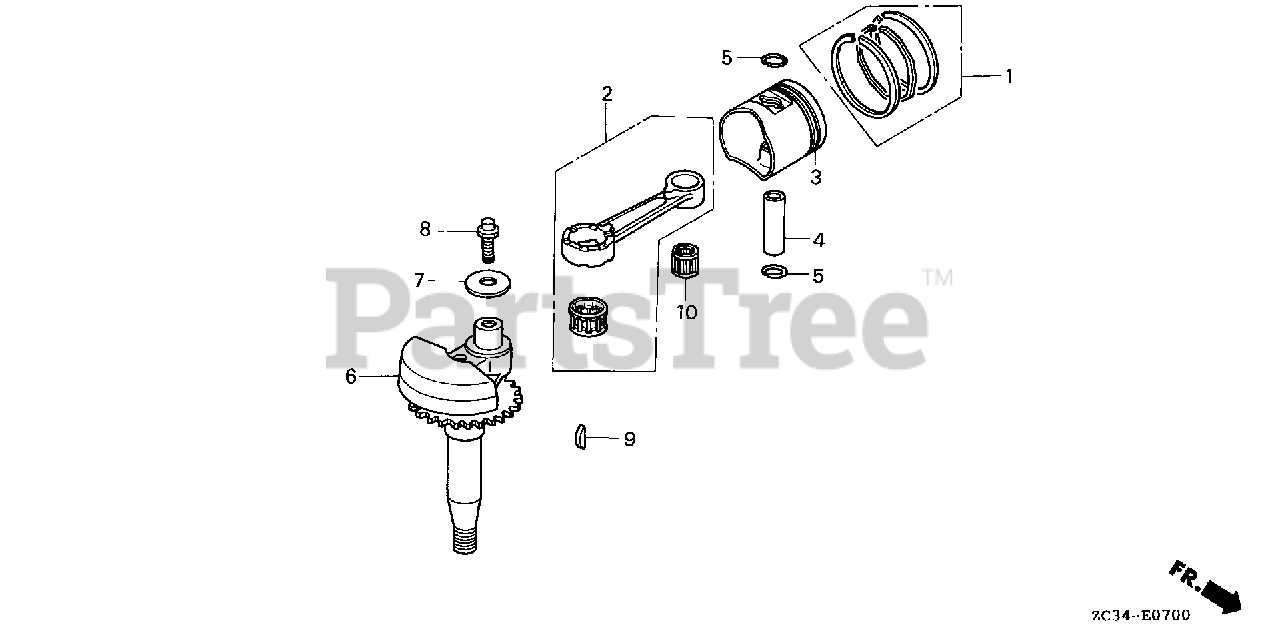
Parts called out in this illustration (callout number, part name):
1	RING SET, PISTON
2	ROD SET, CONNECTING
4	PIN, PISTON
5	CLIP, PISTON PIN
6	CRANKSHAFT
7	WASHER, CAMSHAFT SIDE
8	PIN, RECOIL
9	KEY, WOODRUFF (3MM)
10	BEARING, CONNECTING ROD SMALL END
